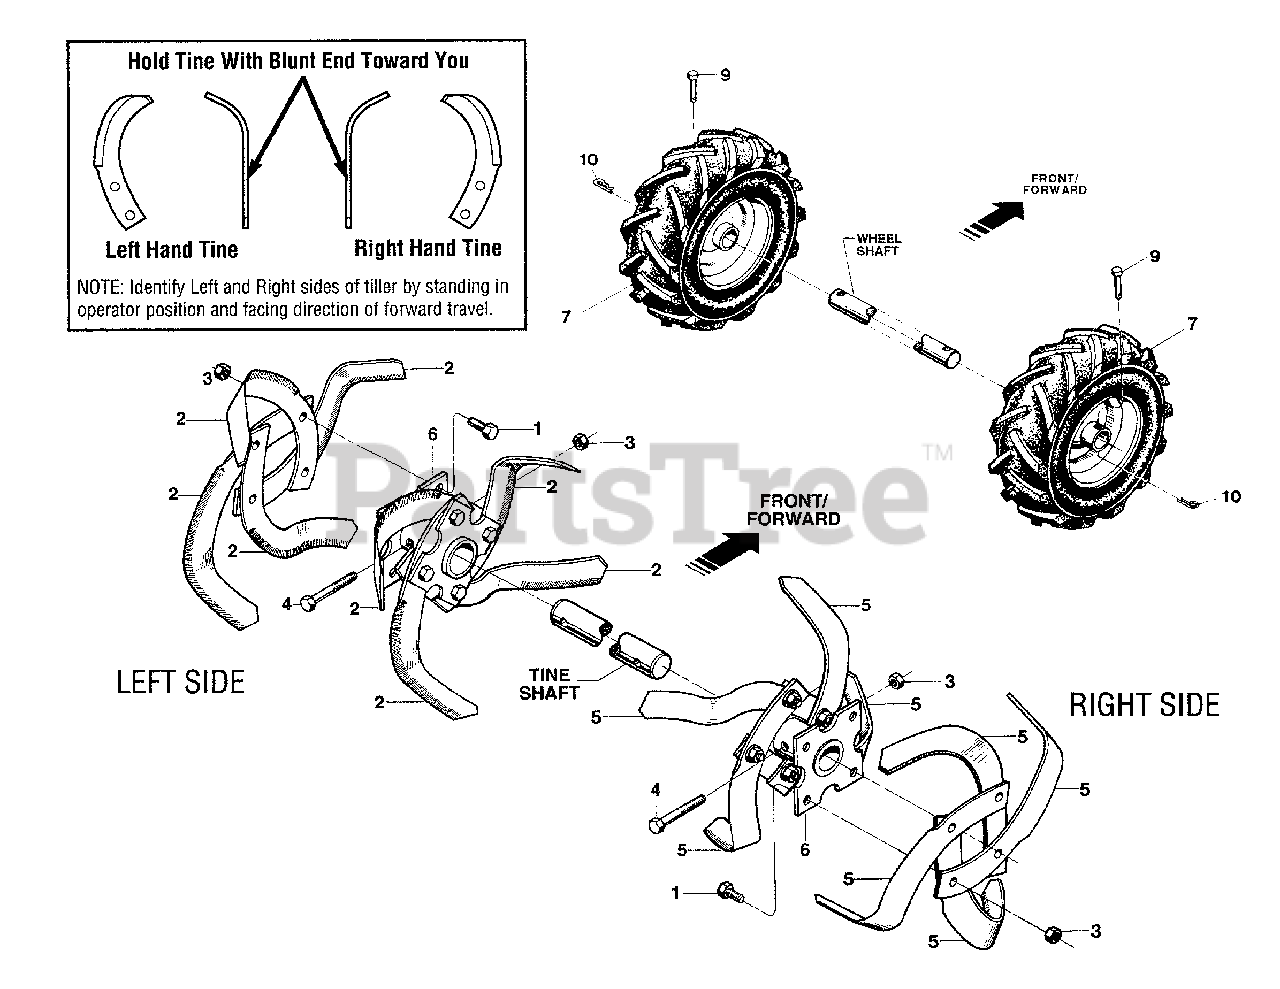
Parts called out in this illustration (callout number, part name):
1	Hex Screw, 3/8-16 x 1, Grade 5
2	Bolo Tine - Right Hand
3	Hex Locknut, 3/8-16
4	Hex Screw, 3/8-16 x 1-3/4
5	Bolo Tine - Left Hand
6	Tine Holder
7	Wheel & Tire Assembly
9	Clevis Pin, .312" x 1-3/4"
10	Hair Pin Cotter
